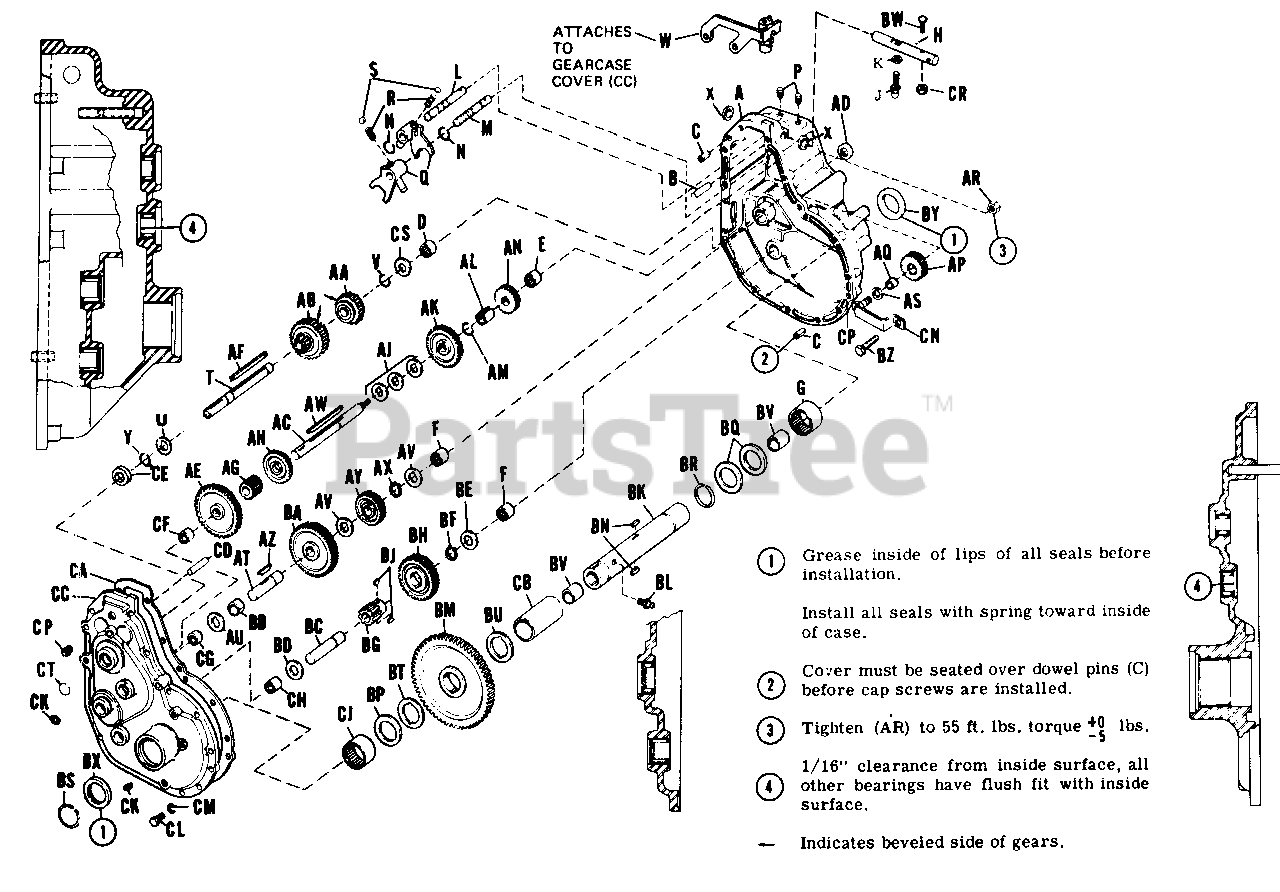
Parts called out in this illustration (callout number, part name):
A	Case, Gear, Complete w/bearings and dowel pins (Includes "B" thru G")
D	Needle Bearing
E	Needle Bearing
F	Needle Bearing
G	Needle Bearing
H	Shift Rod
J	Shift Stem
K	Full Hex. Nut, 3/8"-24 N.F.
L	Shifter Shaft Rev., Med.
M	Shifter Shaft High, Low
N	Retaining Ring
P	Set Screw, Hollow Hd. Cone Pt. 5/16"-18 x 1/2"
S	Shift Lock Ball
T	Pulley Shaft
V	Retaining Ring
W	Switch Support
Y	Retaining Ring
AA	Pinion Assembly Rev. II
AB	Pinion Assembly I and III
AC	Shaft, 1st Intm.
AE	Driven I, Gear
AG	Pinion, 1st Intm.
AH	Pinion, Driven III
AJ	Trans. Gear Spacer
AK	Driven II Gear
AM	Retaining Ring
AN	Reverse Pinion
AP	Reverse Gear
AQ	Rev. Gear Spacer
AR	Lock Nut, 1/2"-20 N.F.
AT	Shaft, 2nd Intm.
AX	Retaining Ring
AY	Pinion, 2nd. Intm.
BA	Gear, 2nd. Intm.
BC	Shaft, 3rd. Intm.
BF	Retaining Ring
BG	Pinion, 3rd. Intm.
BH	Gear, 3rd. Intm.
BJ	Key Woodruff
BK	Axle Tube w/bushing
BL	Grease Fitting
BM	Drive Gear
BT	Axle Tube Washer
BU	Axle Tube Washer
BW	Carriage Bolt, 5/16"-18 x 1
BZ	Hex. Cap Screw, 3/8"-16 x 1 1/4"
CA	Gear Case Gasket
CB	Axle Tube Spacer
CC	Gear Case Cover, Complete w/bearings
CE	Ball Bearing
CF	Needle Bearing
CG	Needle Bearing
CH	Needle Bearing
CJ	Needle Bearing
CK	Pipe Plug, 3/8"
CL	Hex. Cap Screw, 5/16"-18 x 1"
CM	Lock Washer, 5/16"
CN	Rev. Gear Pin Assembly
CP	Pipe Plug, 3/8"
CR	Hex Jam Nut, 5/16"-18
CT	Retaining Ring
